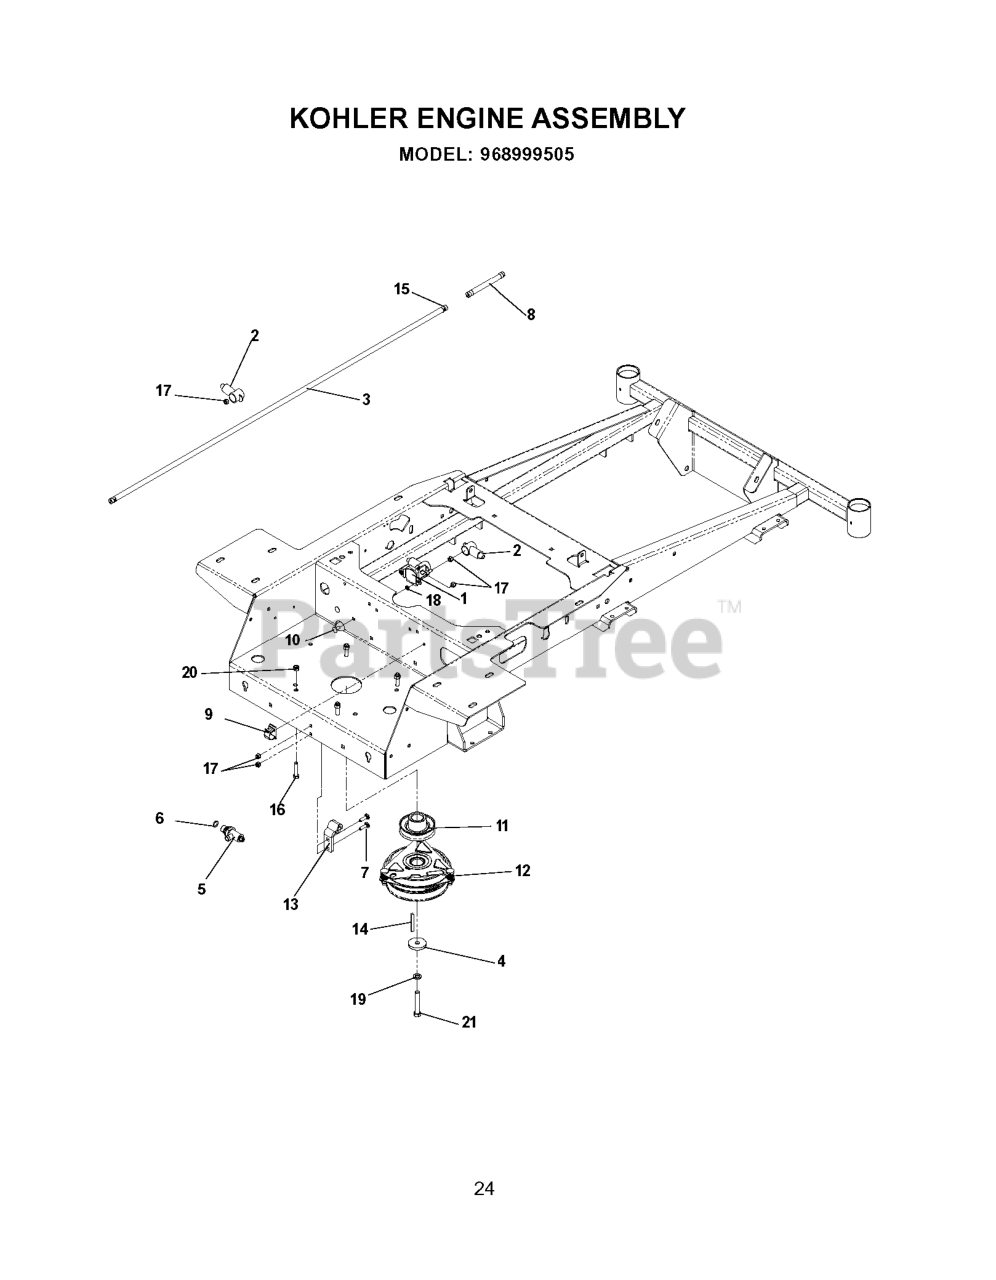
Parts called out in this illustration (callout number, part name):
4	SPINDLE WASHER
5	VALVE ASSEMBLY
7	RHSNB, 1/4-20 X 1, GR5
8	FUEL LINE 5"
9	PUSH-MOUNT WIRE CLIP
10	RHSSNB, 1/4-20X5/8
11	PULLEY, DRIVE
12	CLUTCH, 150 FT/LBS
13	TIE DOWN, CLUTCH
14	KEY 1/4 SQ X 2
15	HOSE CLAMP
16	CAPSCREW 5/16 X 1/1/2 HEX HEAD
17	NUT.1/4-20.HEX.NYLOC.ZD
18	WASHER 1/4 INT TOOTH
19	WASHER 7/16 LOCK
20	NUT 5/16 NYLOC
21	BOLT 7/16F X 2 1/2
